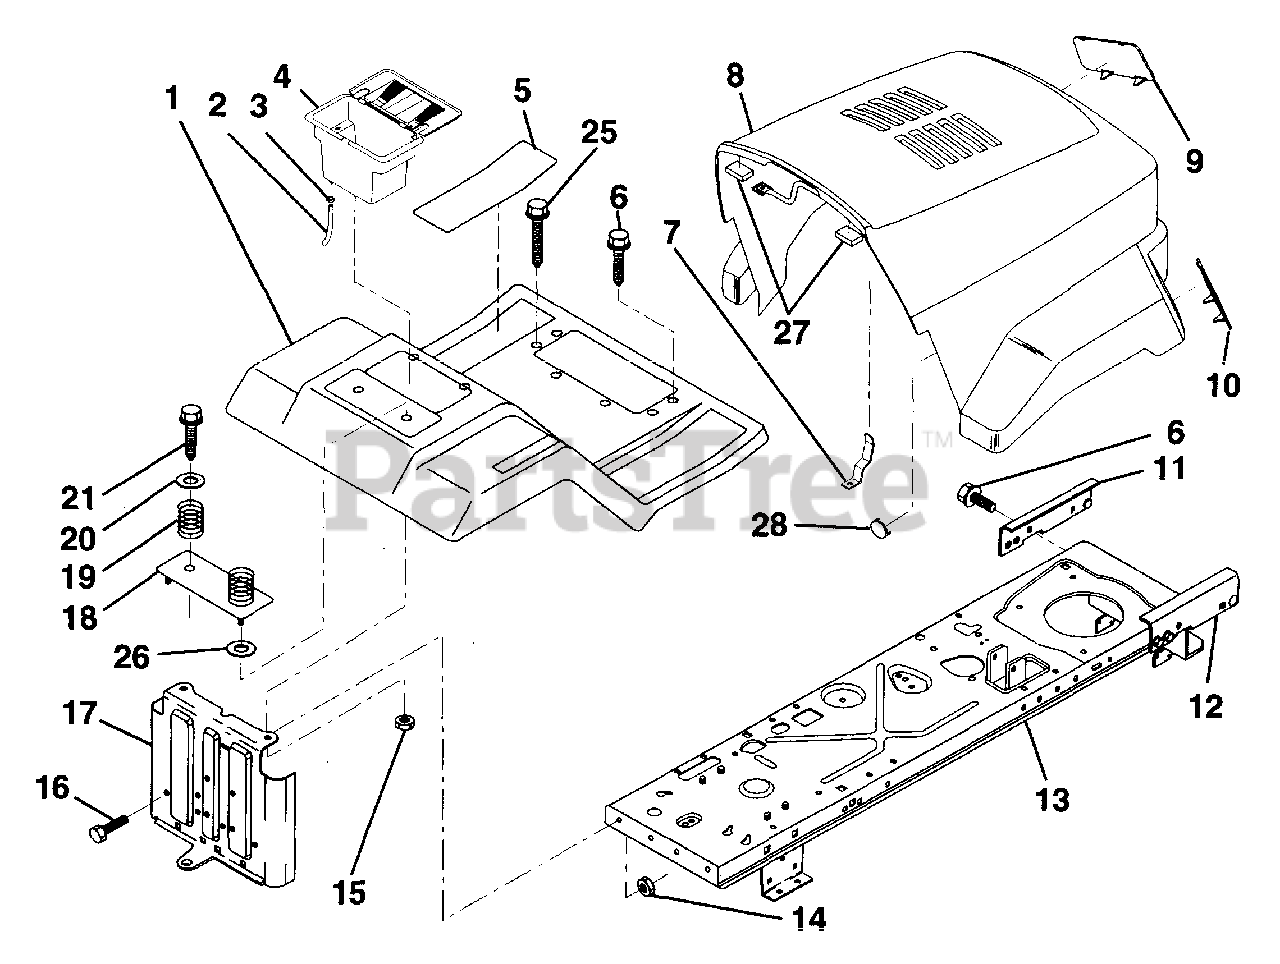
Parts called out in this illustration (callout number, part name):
1	Fender/Footrest
2	Tube, Battery Drain
3	Clamp, Hose
4	Case, Battery
5	Pad, Footrest
6	Screw, Hex Washer Head, Thd., Roll. 5/16-18 x 3/4
7	Latch, Hood
8	Hood/Grill Assembly
9	Lens, L.H.
10	Lens, R.H.
11	Bracket Assy., Pivot, Frame, L.H.
12	Bracket Assy., Pivot, Frame, R.H.
13	Assembly, Frame
14	Nut, Crownlock 5/16-18
15	Nut, Hex, Keps 1/4-20 UNC
16	Bolt, Hex Hd. 5/16-18 UNC x 3/4
18	Plate Assembly, Battery
19	Spring, Compression, Seat
20	Washer 13/32 x 1-1/4 x 12 Gauge
21	Screw, Hex Washer Head, Thd, Roll. 3/8-16 x 3/4
25	Screw, Thrd Rl 5/16 - 18 x 1
26	Washer 9/32 x 7/8 x 13 Gauge
27	Bumper, Hood
28	Plug, Light Socket
